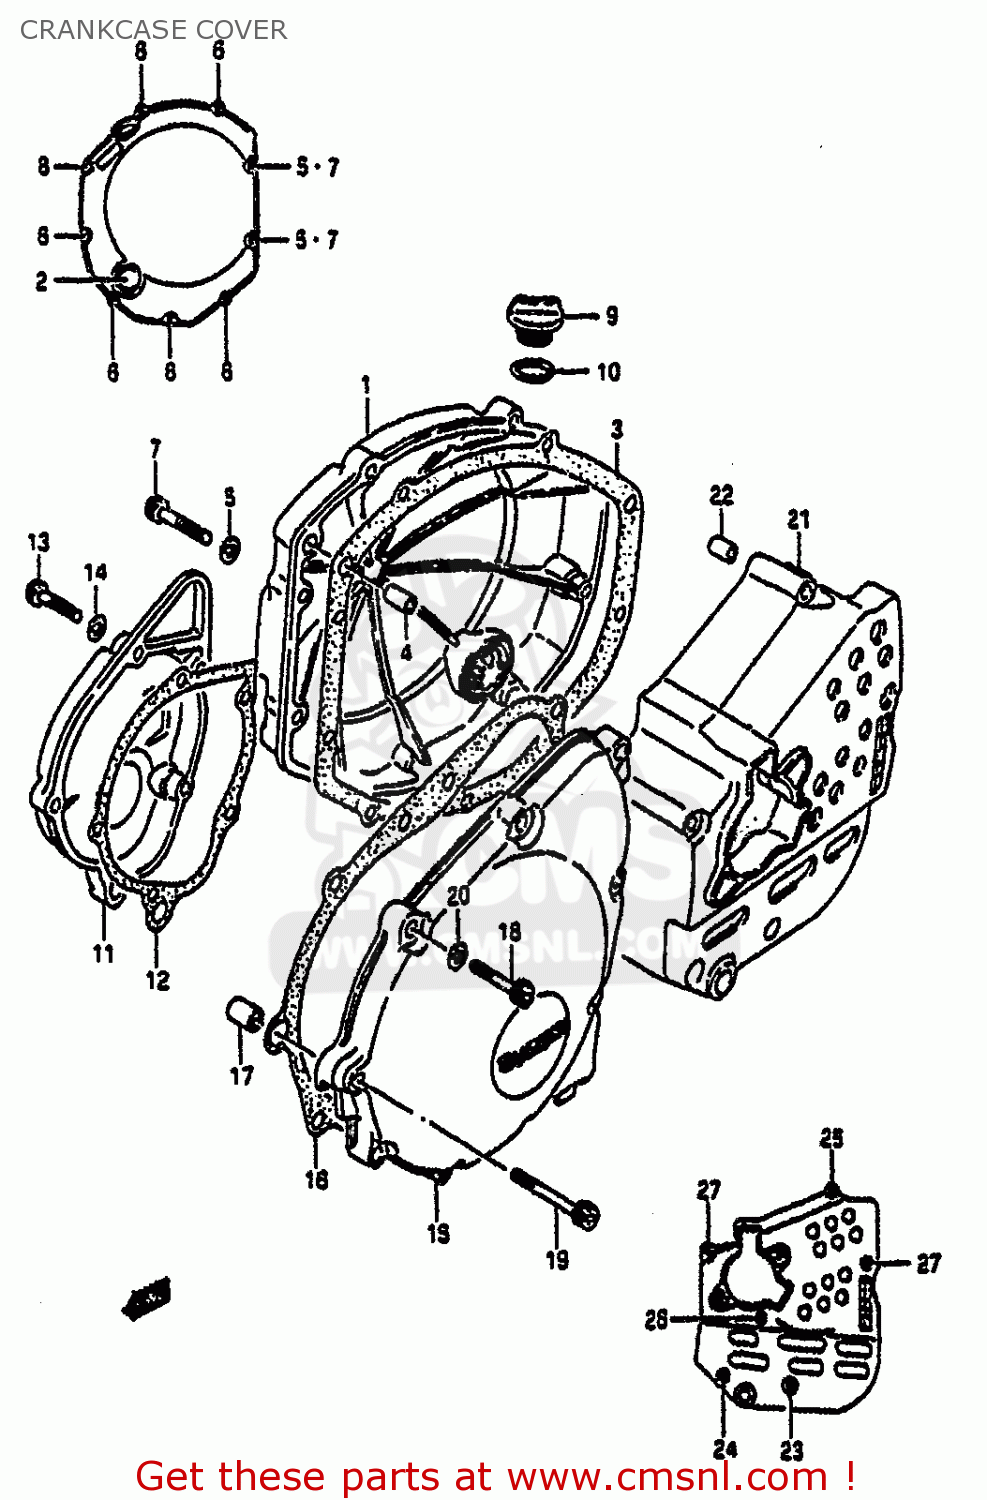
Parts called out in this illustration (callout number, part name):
1	COVER,CLUTCH
2	LENS,OIL LEVEL CHECK
3	GASKET,CLUTCH COVER (NAS)
4	PIN
5	GASKET(5.8X11X1.2) (NAS)
6	BOLT
7	BOLT
8	BOLT
9	PLUG
10	O RING(D:3.1,ID:16.8)
11	COVER,SIGNAL GENERATOR
12	GASKET,SIGNAL GENERATOR COVER (NAS)
13	BOLT
14	GASKET(5.8X11X1.2) (NAS)
15	COVER,STARTER GEAR
16	GASKET,STARTER GEAR COVER (NAS)
17	PIN (11X20)(SUS)
18	BOLT
19	BOLT
20	GASKET(5.8X11X1.2) (NAS)
21	COVER,ENGINE SPROCKET
22	PIN
23	BOLT
24	BOLT
25	BOLT
26	BOLT
27	BOLT
